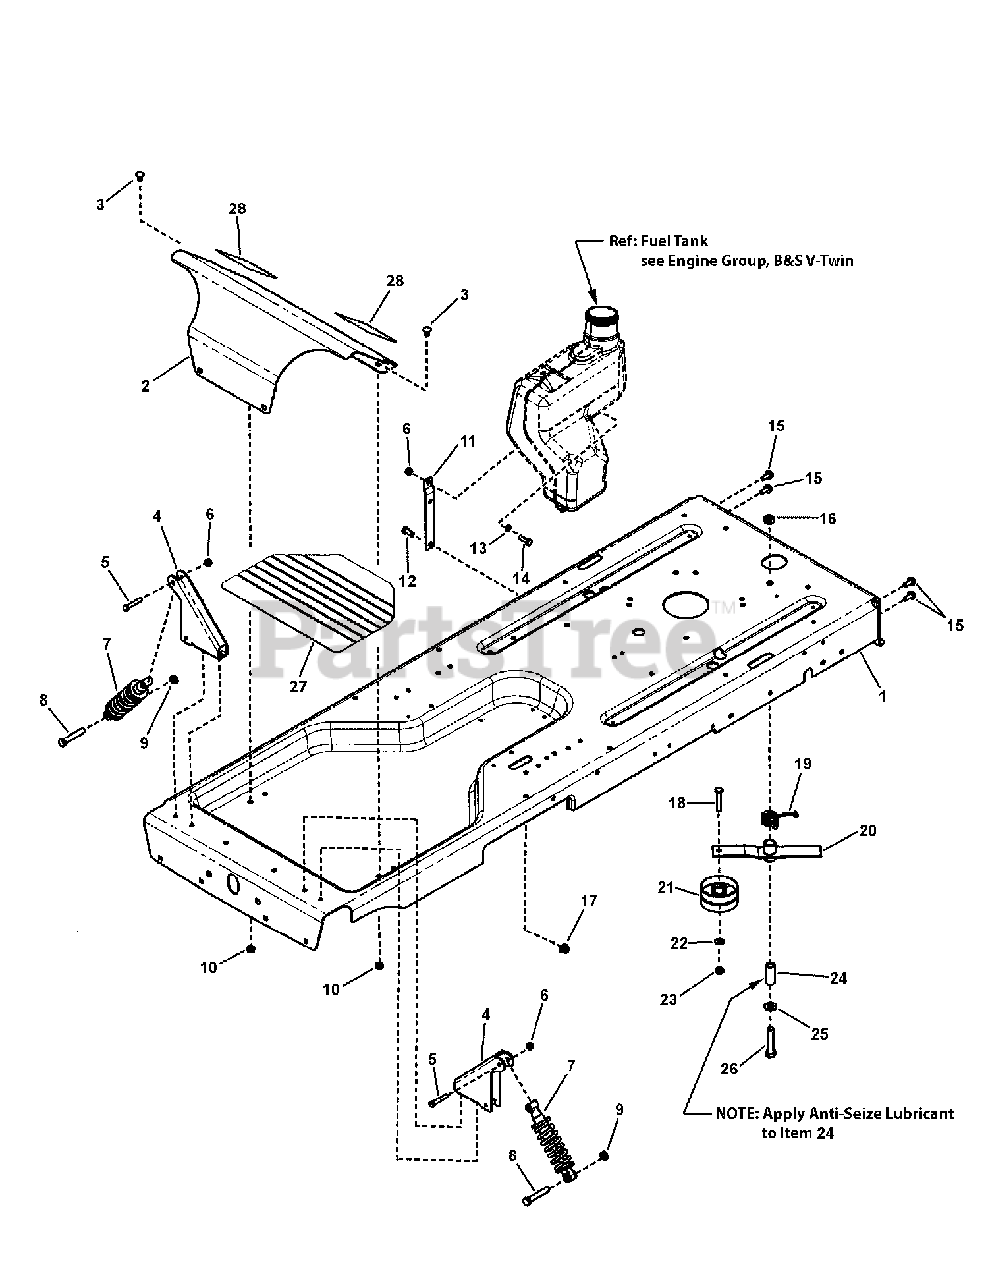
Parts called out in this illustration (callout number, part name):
1	FRAME, RZT
2	FOOTREST, Simplicity
3	BOLT, 5/16-18 x 5/8" Round Head Short Square Neck Carriage, GR 5
4	BRACKET, Shock
5	SCREW, 5/16-18 X 1-3/4"Hex Head Cap, GR 5 Yellow Zinc
6	NUT, 5/16-18- Nyloc, YZ
7	SHOCK
8	SCREW, 7/16-20 x 2-1/2", Hex Head Cap Screw, GR 5, YZ
9	NUT, 7/16-20 Hex Center lock Jam
10	NUT, 5/16-18, Hex Flange Lock, GR 5
11	BRACKET, Support, Fuel Tank
12	SCREW, 3/8-16 x 3/4" Hex Head Cap, GR 5
13	WASHER, .34 x .62 x 16 Ga, Flat
14	SCREW, 5/16-18 x 1" Hex Head Cap, GR 5, YZ
15	SCREW, 5/16-18 x 3/4" Hex Washer Self-Tap, YZ
16	NUT, 1/2-13 Hex Center Lock, GR 5, YZ
17	NUT, 3/8-16 Hex Flange lock, GR F, BZ
18	SCREW, 3/8-16 x 2" Hex Head Cap, GR 5, YZ
19	SPRING, Torsion, RH Wind
20	WELDMENT, Hydro Idler MY08
21	IDLER, 3.25" OD x .391 ID x 1.63, Backside
22	WASHER, 3/8" Flat (SAE)
23	NUT, 3/8-16 Hex Center Lock, YZ
24	SPACER, Hydro Idler
25	WASHER, .531 x 1.062 x .121, Flat, YZ (SAE)
26	SCREW, 1/2-13 x 2-1/2", Hex Head Cap, GR 5 (Black Phosphate)
27	MAT, Floor Pan
28	SAFETY, Walk, 7.25 x 5.25
